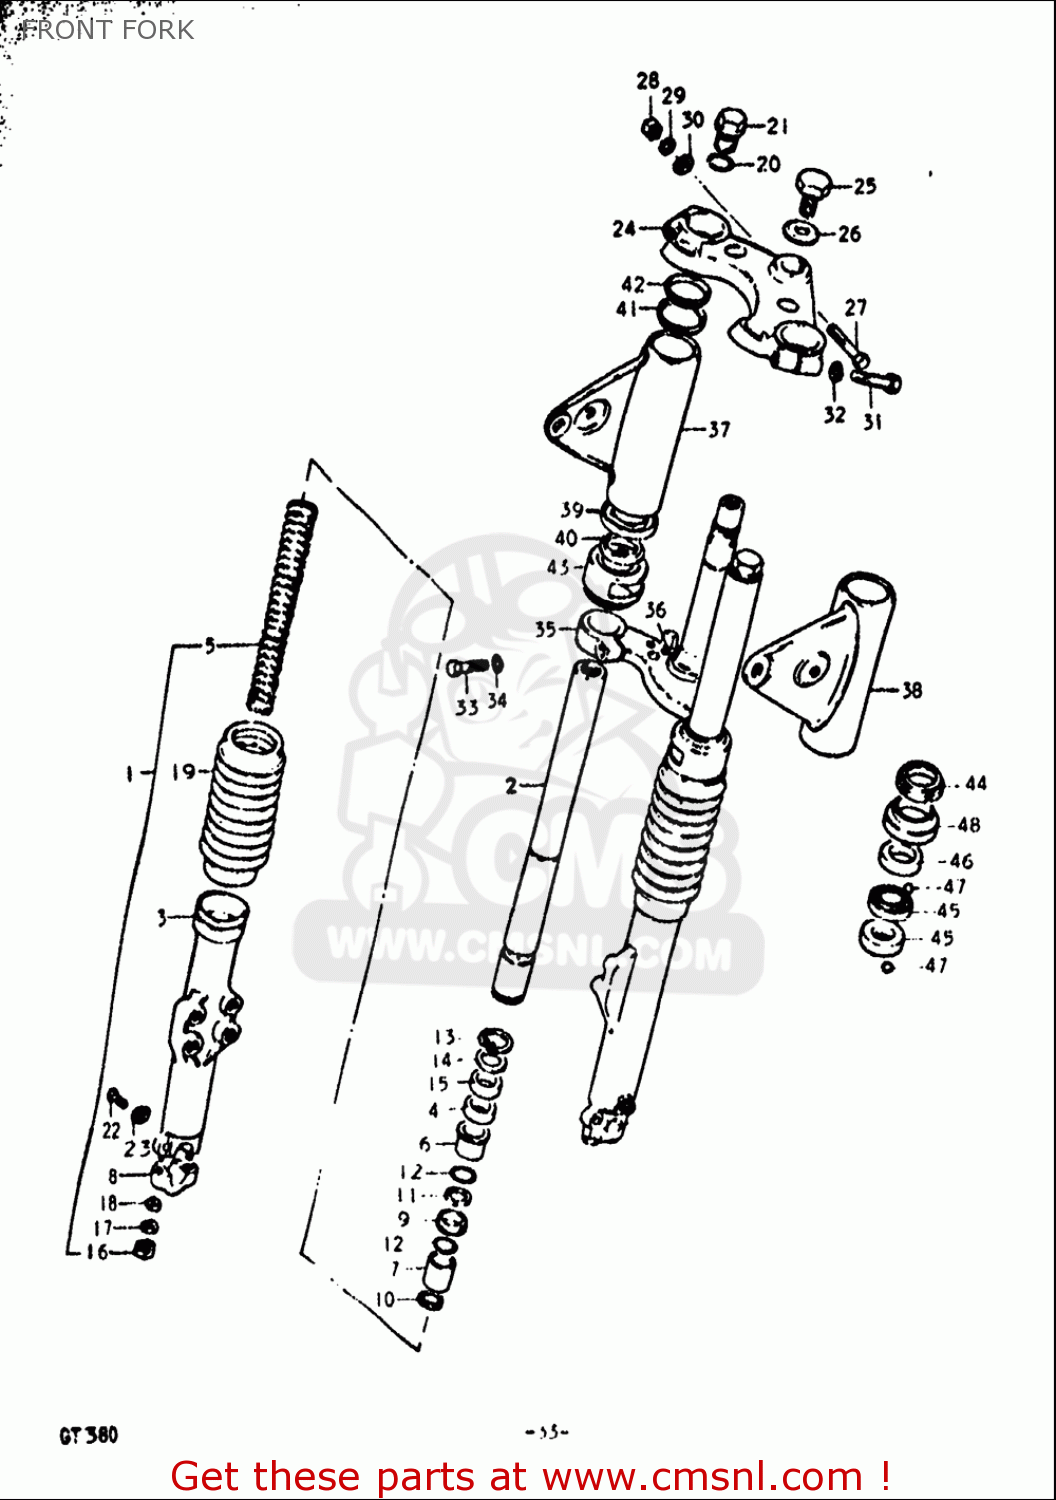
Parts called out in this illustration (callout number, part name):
8	HOLDER,AXLE
15	SEAL,OIL
16	NUT
17	WASHER,LOCK
18	WASHER
19	BOOT
22	SCREW 4X6
23	GASKET (NAS)
27	BOLT
28	NUT
29	WASHER,LOCK
30	WASHER
31	BOLT
32	WASHER,LOCK
33	BOLT
34	WASHER,LOCK
36	RACE,STEERING OUTER LWR
39	GUIDE
40	CUSHION,HEADLAMP BRACKET
41	GUIDE
42	CUSHION,HEADLAMP BRACKET UPR
44	NUT,STEERING STEM(25X44X10)
45	LACE,STEERING INNER LWR
46	LACE,STEERING OUTER UPR
47	BALL
48	DUST SEAL,STEERING UPR
